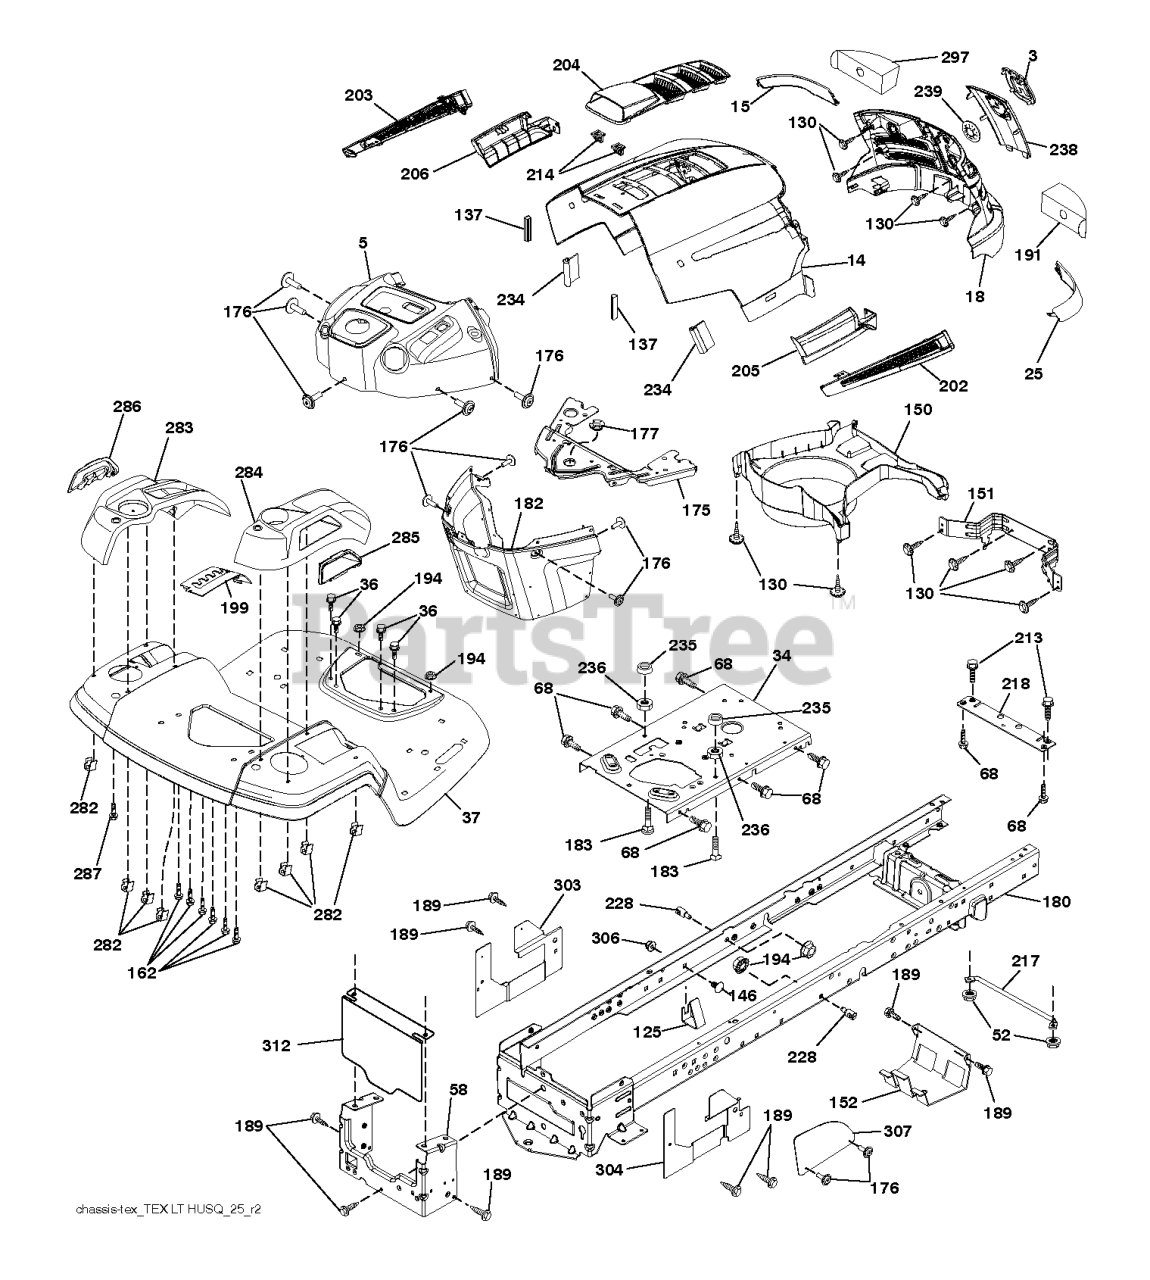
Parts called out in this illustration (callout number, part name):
3	RP LOGO
5	SUBASM.DASH.UPPER.HLT.498
14	HOOD
15	LENS.HUSQVARNA LT.RH
18	GRILLE.SVC.HUSQVARNA.GREY
25	LENS.HUSQVARNA LT.RH
34	PLATE PLATE ENGINE
36	SCREW 5/16"
37	FENDER.TLT.FS.W/CUPHLD.ORANGE
52	LOCKNUT
58	DRAWBAR UPPER 2PC SMALL FENDER
68	Screw 5/16-18 x 1/2 Hex, Self Tapping 5/16-18 x 1/2
125	CLIP.FUEL.LINE
130	SCREW.#10 X 0.750.BOS
137	BUMPER DASH
146	BOLT.RDHD.SHT.SQNK.3/8-16X5/8
151	BRACKET PIVOT
152	SHIELD.BROWNING.W/TEX
162	SCREW.HI-LO.CONSOLE
175	CROSSMEMBER
176	SCREW.#10-24X5/8.RN.QU
177	BUSHING STEERING
180	CHASSIS.WLDMNT.14GA.2PC.18".TI
182	DASH.LOWER.PREDATOR LT
183	BOLT.5/16-18X1-1/4 FULL THD
189	SCREW
191	INSERT.REFLECTIVE.RH.
194	NUT LOCK HEX FLANGE 5/16-18
199	PLATE.DECK.LIFT.HUSQ.LT
202	VENT.SIDE.HUSQVARNA.LT.RT
203	VENT.SIDE.HUSQVARNA.LT.LFT
204	SUBASM.TOP.VENT.HUSQ.LT
205	SKIRT.SIDE.HUSQVARNA.LT.RT
206	SKIRT.SIDE.HUSQVARNA.LT.LEFT
213	BOLT
214	CLIP.RETAINER.TINNER.
217	ROD.PIVOT.HOOD
218	X-PIECE.HOOD.STOP.NON/
228	STUD.FASTNER.W/ANTI-ROTATE
234	BUMPER.HOOD.TEX.HUSQVARNA
235	SPACER FENDER
236	NUT.CENTERLOCK.5/16-
238	TRIM.HUSQ LT.668
282	CLIP.RETAINER.CONSOLE.LT.HUSQ
283	CONSOLE.ASM.LFT.RSF.HUSQ.LT
284	CONCOLE.CNTRL.PDL.HUSQ.LT.498
285	CONSOLE INSERT RH
286	CONSOLE.INSRT.LH.HUSQ.LT.BLACK
287	SCREW 1/4X20
297	INSERT REFLECTIVE
303	SHIELD CHASSIS LEFT
306	NUT LOCK FLG 3/8-16 UNC
307	SHIELD UPPER PEDAL
312	SHIELD.PNT.DRAWBAR.FRENCH
